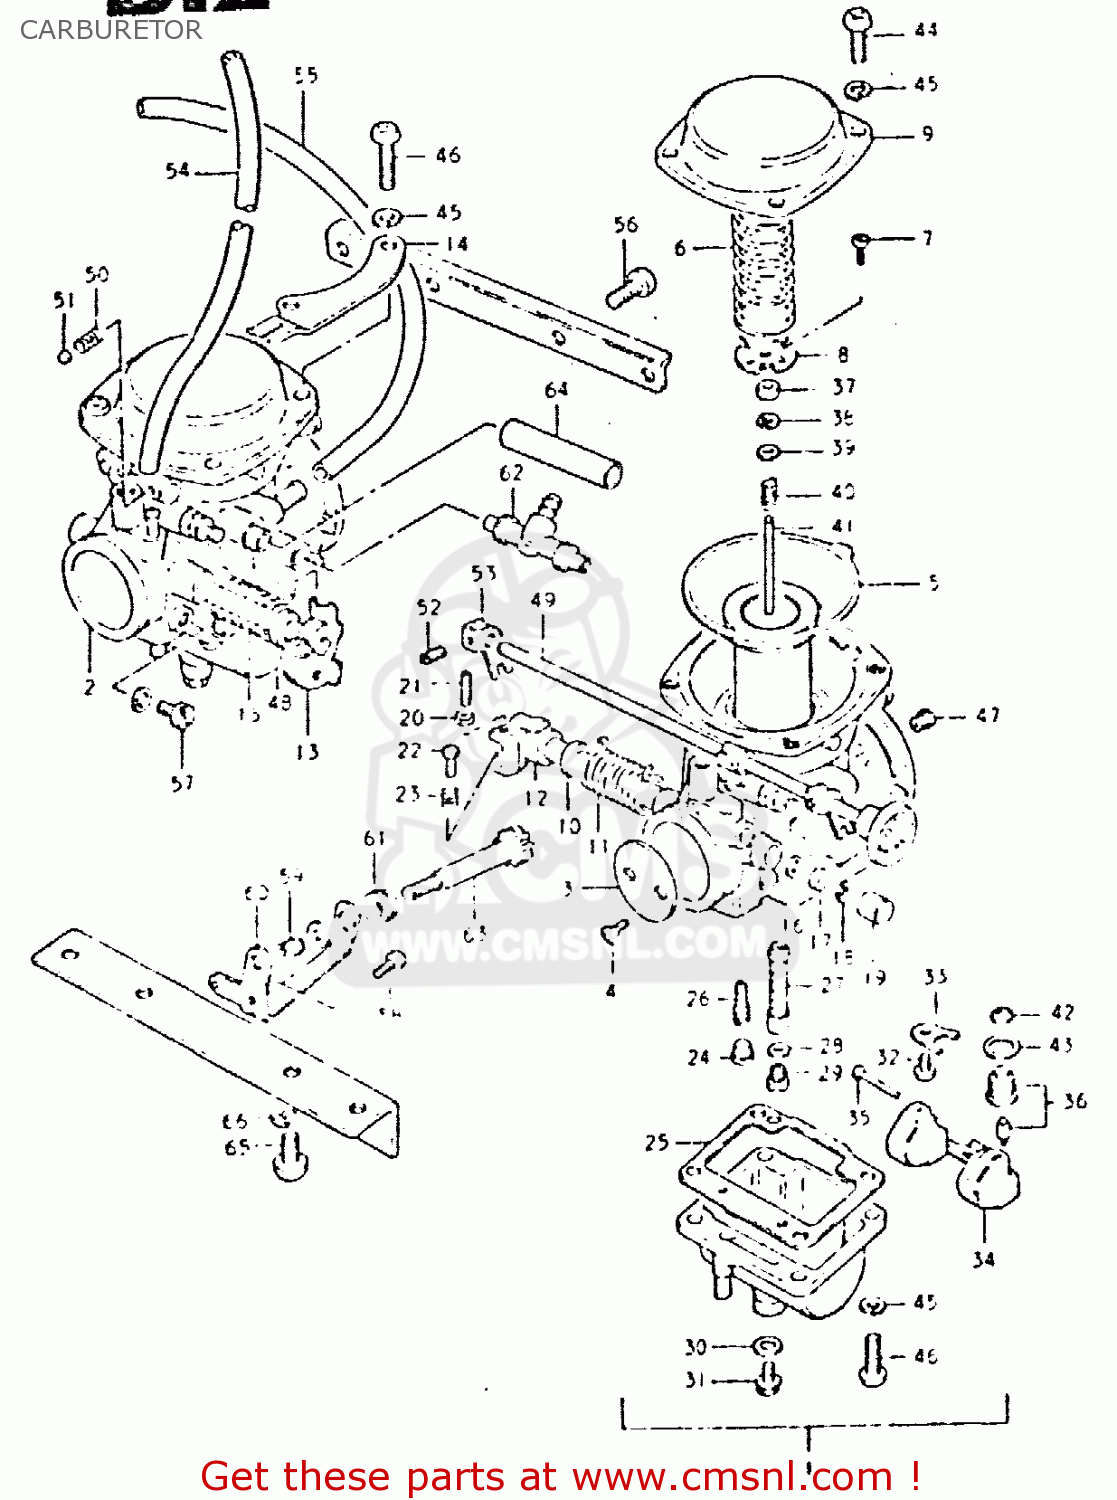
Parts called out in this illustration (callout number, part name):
1	CARBURETOR, LH
2	CARBURETOR, RH
3	VALVE, THROTTLE (135)
4	SCREW
5	DIAPHRAGM,CARBURETOR
6	SPRING
7	SCREW
8	PLATE
9	COVER,DIAPHRAGM
10	SPACER,THROTTLE SHAFT
11	SPRING
12	SHAFT
13	SHAFT
14	BRACKET
15	SPRING
16	SEAL
17	GASKET,THROTTLE SHAFT (NAS)
18	E RING
19	CAP
20	NUT
21	SCREW
22	PIN,THROTTLE LEVER
23	SPRING,THROTTLE SCREW
24	PLUG,NEEDLE JET
25	GASKET,FLOAT CHAMBER (NAS)
26	JET, PILOT (42.5)
27	JET,NEEDLE(P-1)
28	WASHER,NEEDLE NOZZLE
29	JET
30	GASKET (NAS)
31	PLUG,DRAIN
32	SCREW 4X6
33	PLATE
34	FLOAT
35	PIN,FLOAT
36	VALVE ASSEMBLY,NEEDLE
37	RING
38	CLIP
39	PIN,FLOAT
40	SPRING
41	NEEDLE,JET
42	FILTER
43	O-RING,NEEDLE VALVE
44	SCREW
45	LOCK WASHER
46	SCREW
47	JET,AIR(125)
48	SPACER,THROTTLE SHAFT
49	SHAFT
50	SPRING
51	BALL,CARBURETOR
52	SCREW
53	LEVER
54	HOSE
55	HOSE
56	SCREW
57	SCREW
58	SCREW
59	SPRING,THROTTLE ADJUST
60	BRACKET
61	CAP
62	NIPPLE,CARBURETOR
63	SCREW
64	HOSE
65	SCREW 6X12
66	LOCK WASHER
